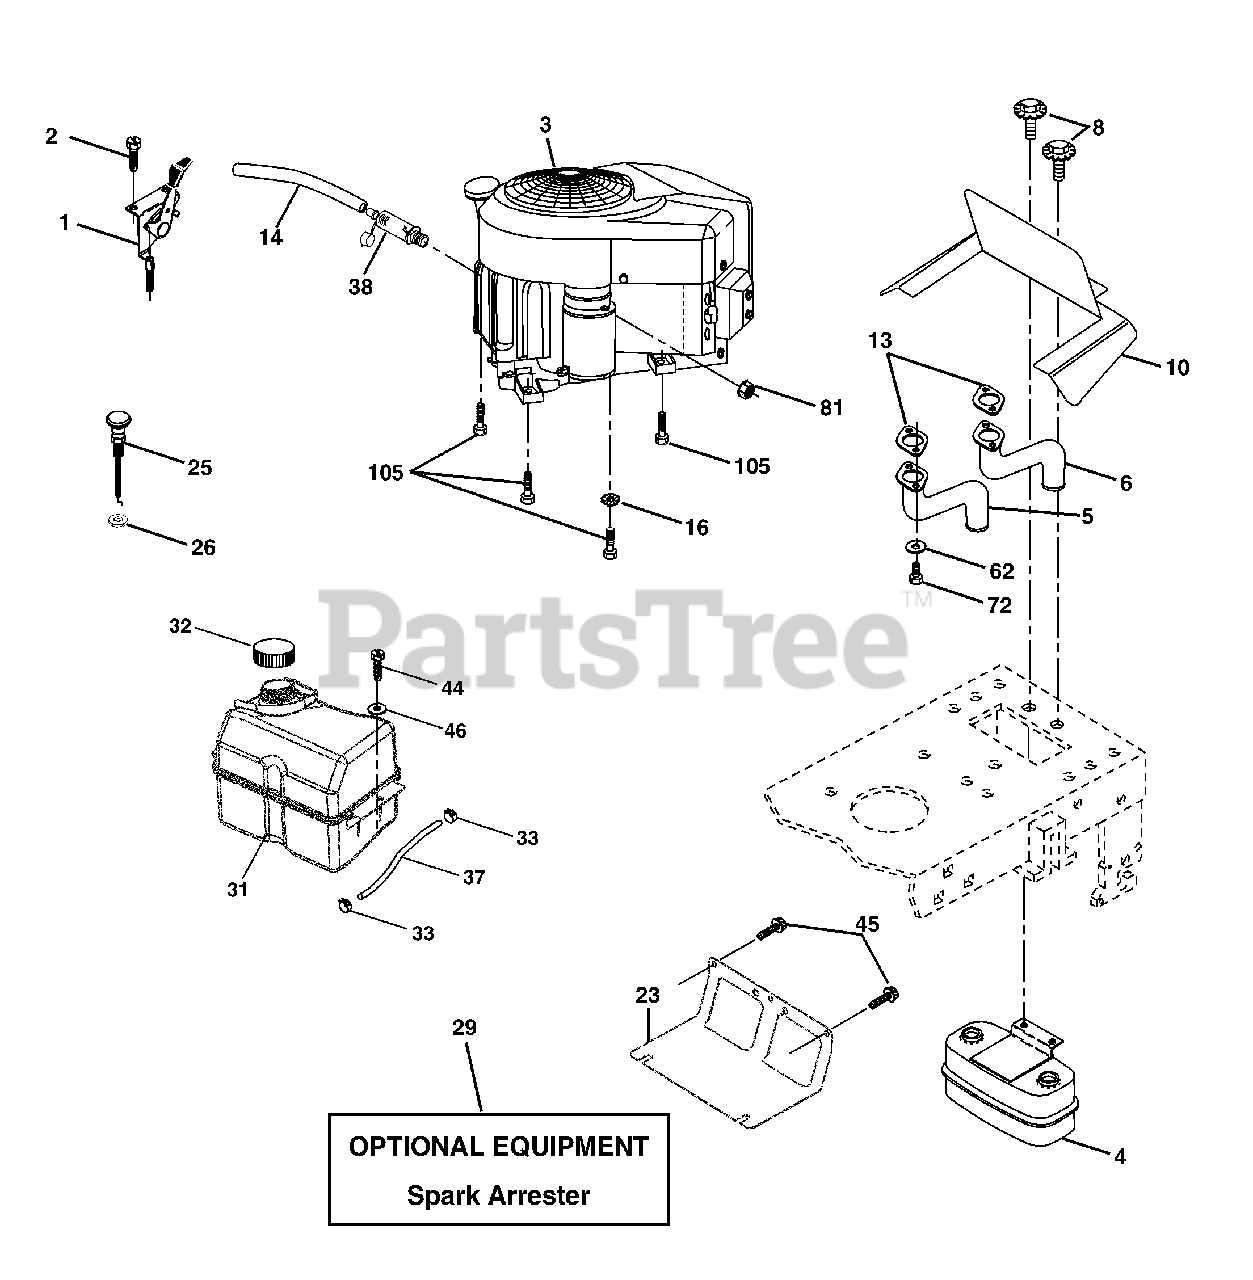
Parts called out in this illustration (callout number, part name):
1	Control Throt /Ch Flag
2	Screw Hex Thd Cut 1/4-20x1/2
4	Muffler Exhaust
5	Exhaust Tube LH
6	Exhaust Tube RH
8	Bolt 5/16-18unc x 3/4 W/Sems
10	Shield Muffler
13	Gasket
14	Tube Drain Oil Easy
16	Washer Lock Ext Tooth 3/8
23	Shield Browning/Debris Guard
25	Control Choke
26	Nut Keps 3/8-24 Unf
29	Arrestor Spark
31	Tank Fuel
32	Cap Asm Fuel W/sym Vented
33	Clamp Hose Blk
37	Line Fuel 20"
38	Plug Drain Oil Easy
44	Screw Hexwsh Thdrol 1/4-20x3/4
45	Screw Hex Wsh Thdrol 3/8-16
46	Washer 9/32 X 7/8 X 16 ga
62	Washer Lock Hvy HLCL Spr 5/16
72	Screw Hex Hd Cap 5/16-18 x 3/4
81	Nut Keps Hex 1/4-20 Unc
105	Screw 3/8-16 x 1 SMGML Tap/R
